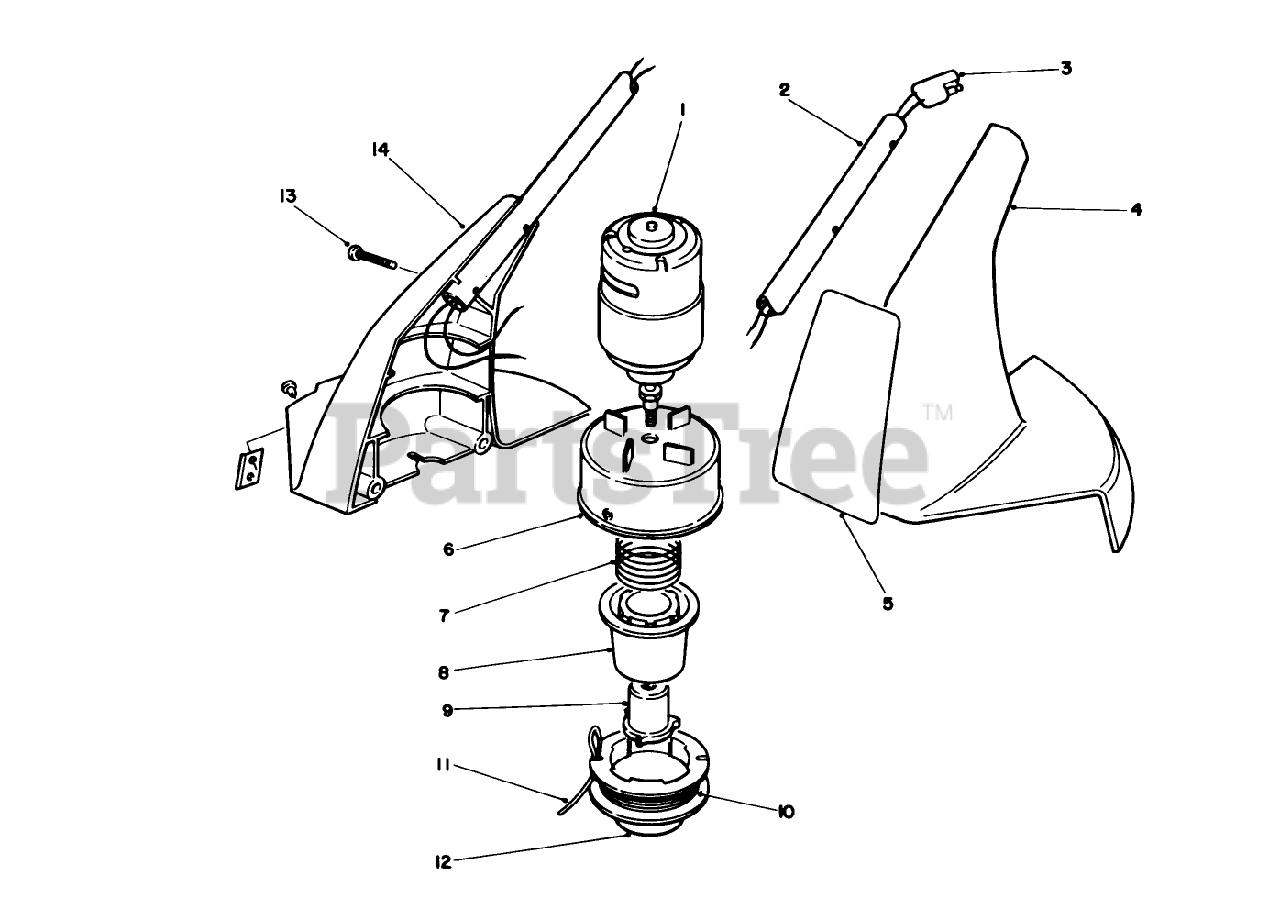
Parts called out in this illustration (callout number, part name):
2	HANDLE-EXTENSION
3	WIRING HARNESS-LOWER
6	DRUM ASM-4 BLADE
7	SPRING-COMPRESSION
8	CORE - SPOOL
9	DRIVER
10	Cutting Line (12- .05 Dia.)
11	CAP-SPOOL
12	Line-Cutting (30- .05 Dia.)
13	SCREW-PLASTITE
14	RH MOTOR HOUSING ASSY.
